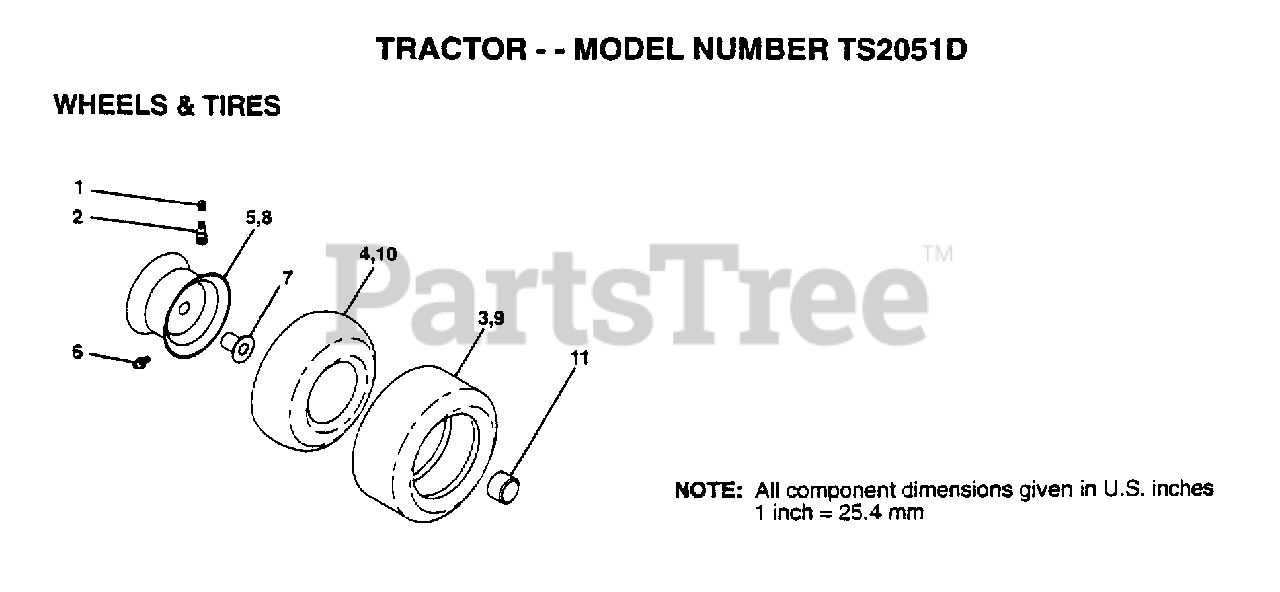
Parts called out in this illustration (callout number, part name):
1	VALVE CAP
2	VALVE STEM LT
4	TUBE.16X6.5/7.5-8
5	RIM.FRONT.
6	ZERK FITTING M
7	"FLANGE, BEARING"
8	"WHEEL,REAR"
10	TUBE.23X8/10-12
11	HUB CAP
12	FITTING LT
